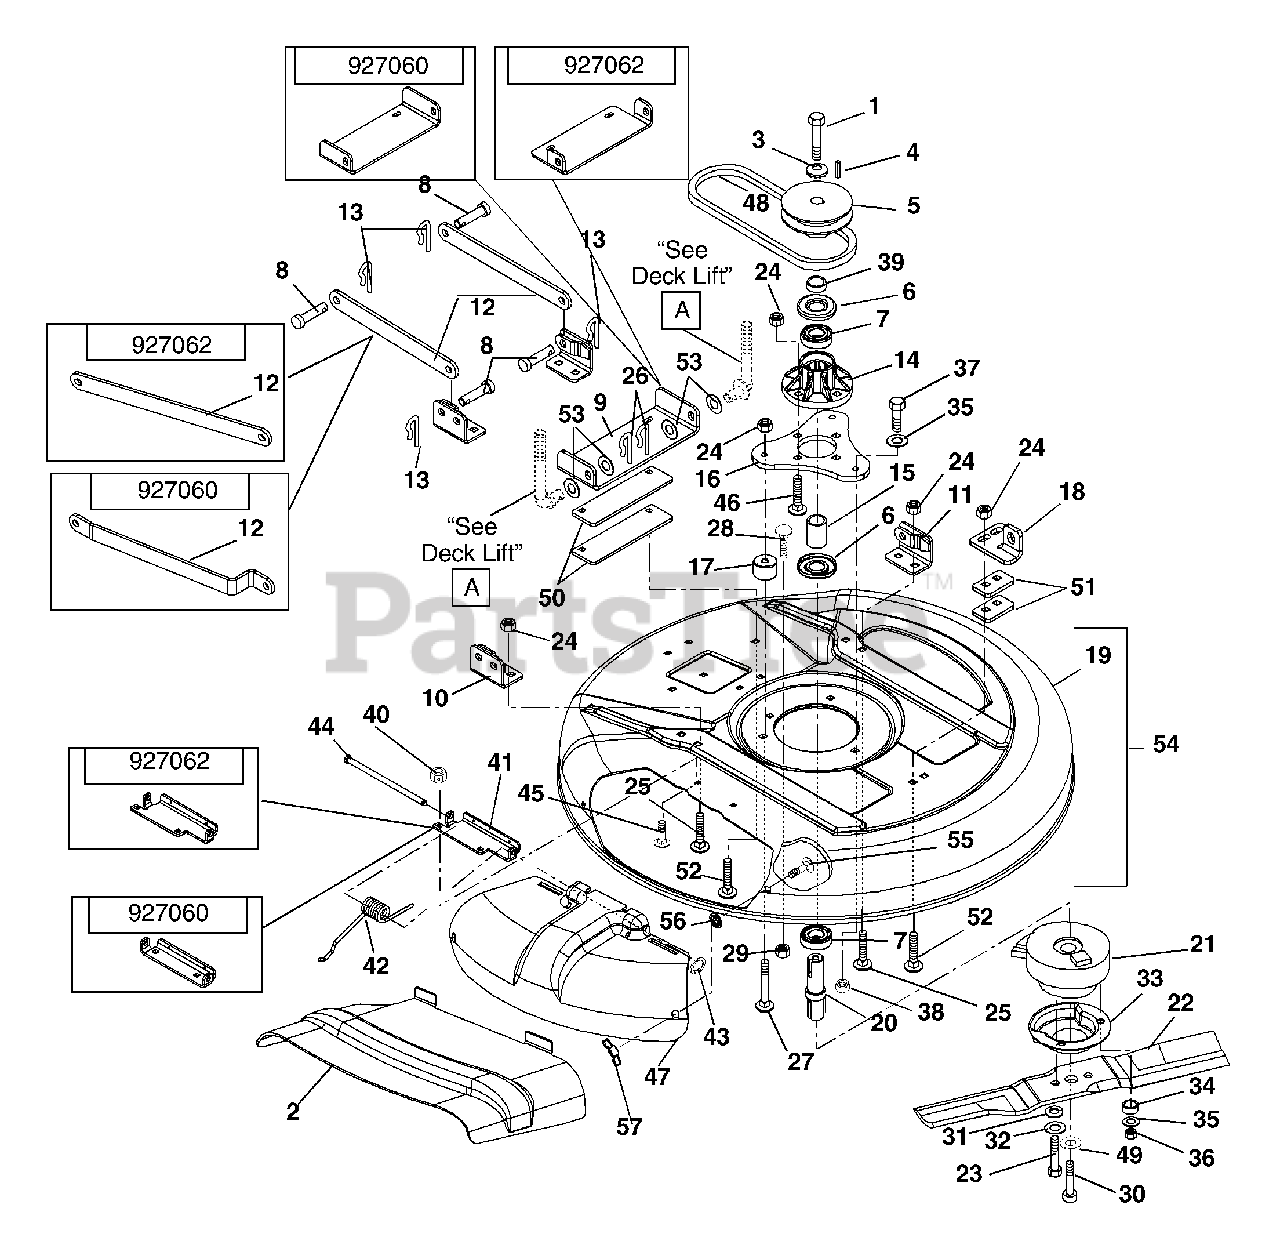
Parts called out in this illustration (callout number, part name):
1	Bolt, Hex .38-16 x 1.00 Grade 8 with Epoxy Patch
2	Discharge Chute
3	Washer, Cupped Serrated .375
4	Key, Square .25 x .38 x .25
5	Pulley, 28" Deck Input (060)
5	Pulley, 32" Deck Input (062)
6	Bearing, Slinger
7	Bearing, Ball 1.00 x 2.00 x .56
8	Pin, Clevis .494 x 1.00
9	Bracket, Rear Hanger 28" (060)
9	Bracket, Rear Hanger 32" (062)
10	Bracket, Deck Link Right Hand (060)
10	Bracket, Deck Link Right Hand (062)
11	Weldment, Deck Link Right Hand (060)
11	Weldment, Deck Link Left Hand (062)
12	Stabilizer , 28" Deck (Right Hand Only) (060)
12	Link Stabilizer (060)
12	Link Stabilizer (062
13	Clip, Spring
14	Assembly, Spindle Housing
15	Spacer, 1.00 x 1.25 x 1.60
16	Spindle, Mount Plate
17	Spacer, Mounting Plate
18	Bracket, Front Lift Hanger (060)
18	Bracket, Front Lift Hanger (062)
19	Deck, 28"(060)
19	Deck, 32" (062)
20	Shaft, 32" Input
21	Clutch, 28" & 32" Decks
22	Blade, 28" Mower (060)
22	Blade, 32" Mower (062)
23	Bolt, Hex M10 x 1.25 x 30
24	Nut, Locking Top Flange .38-16
25	Bolt, Round Head Square Neck .38-16 x .75 Grade 5
26	Pin, Hair External- #11
27	Bolt, Round Head Square Neck .38-16 x 2.25 Grade 5
28	Bolt, Round Head Square Neck .31-18 x 1.50 Grade 5
29	Nut, Spin Lock Flange .312-18
30	Bolt, Button Head .50 x 1.25-20
31	Washer, Locking Metric 10 MM
32	Washer, Flat Steel .406 x 1.00 x .188
33	Shield, Debris
34	Bushing, Bronze .75 I.D. x .88 O.D. x .50 Long
35	Washer, Flat Steel .38 x .875 x .083
36	Nut, Locking Nylon .38-16
37	Bolt, Hex .38-16 x 3.00 Grade 5
38	Nut, Flange .375-16
39	Spacer Steel 1.01 x 1.38 x .509
40	Nut, Locking Center .25-20
41	Bracket, 28" Mulch Cover Hinge
41	Bracket, 32" Mulch Cover Hinge
42	Spring, Torsion
43	Ring, Retaining External .312 x .025
44	Rod, Hinge
45	Bolt, Round Head Square Neck .25-20 x .75 Grade 5
46	Bolt, Round Head Square Neck .38-16 x 1.25 Grade 5
47	Cover, 28" Deck Mulch
47	Cover, 32" Deck Mulch
48	V-Belt HA, 57.25 (060)
48	V-Belt HA, 63.00 (062)
49	Washer, Flat Steel .50 x 1.75 x .187
50	Plate, 32" Deck Spacer
51	Plate, 32 Deck Front Hanger
52	Bolt, Round Head Square Neck .38-16 x 1.25
53	Washer, Flat Steel .518 x 2.00 x .105
54	Kit, 28" Deck Assembly Service (060)
54	Kit, 32" Deck Assembly Service (062)
55	Bolt, Round Head Square Neck .31-18 x .75 Grade 2
56	Nut, Push .312
57	Nut, Nylock Wing .312-18
